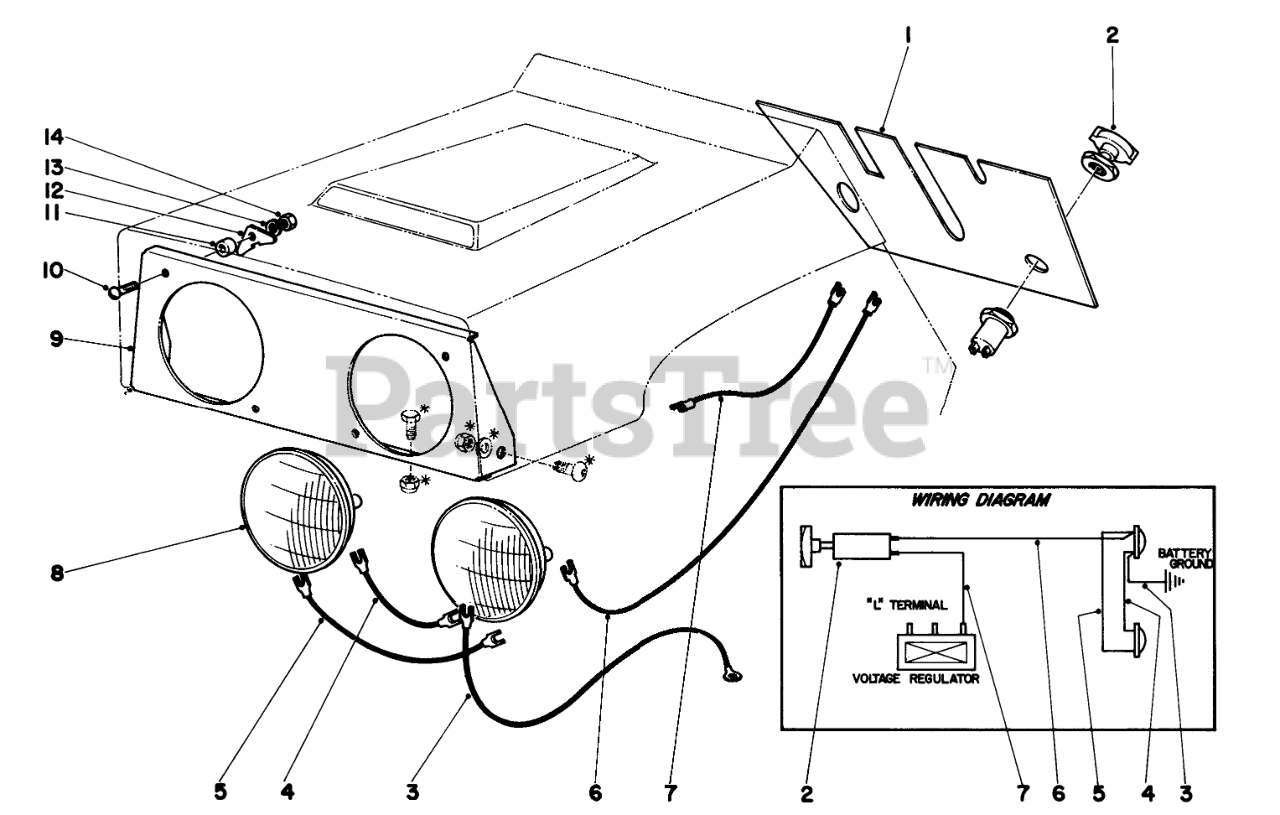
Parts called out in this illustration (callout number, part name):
1	Paper Template
2	Light Switch
3	Wire Assy.-Red
4	Wire 960
5	Wire 960
6	Wire Assy.
7	Wire 960
8	HEAD LAMP
9	Panel-Headlight
10	SCREW-SRH
11	Spacer
12	Clip 960
13	WASHER-LOCK/SP
14	NUT-HEX
